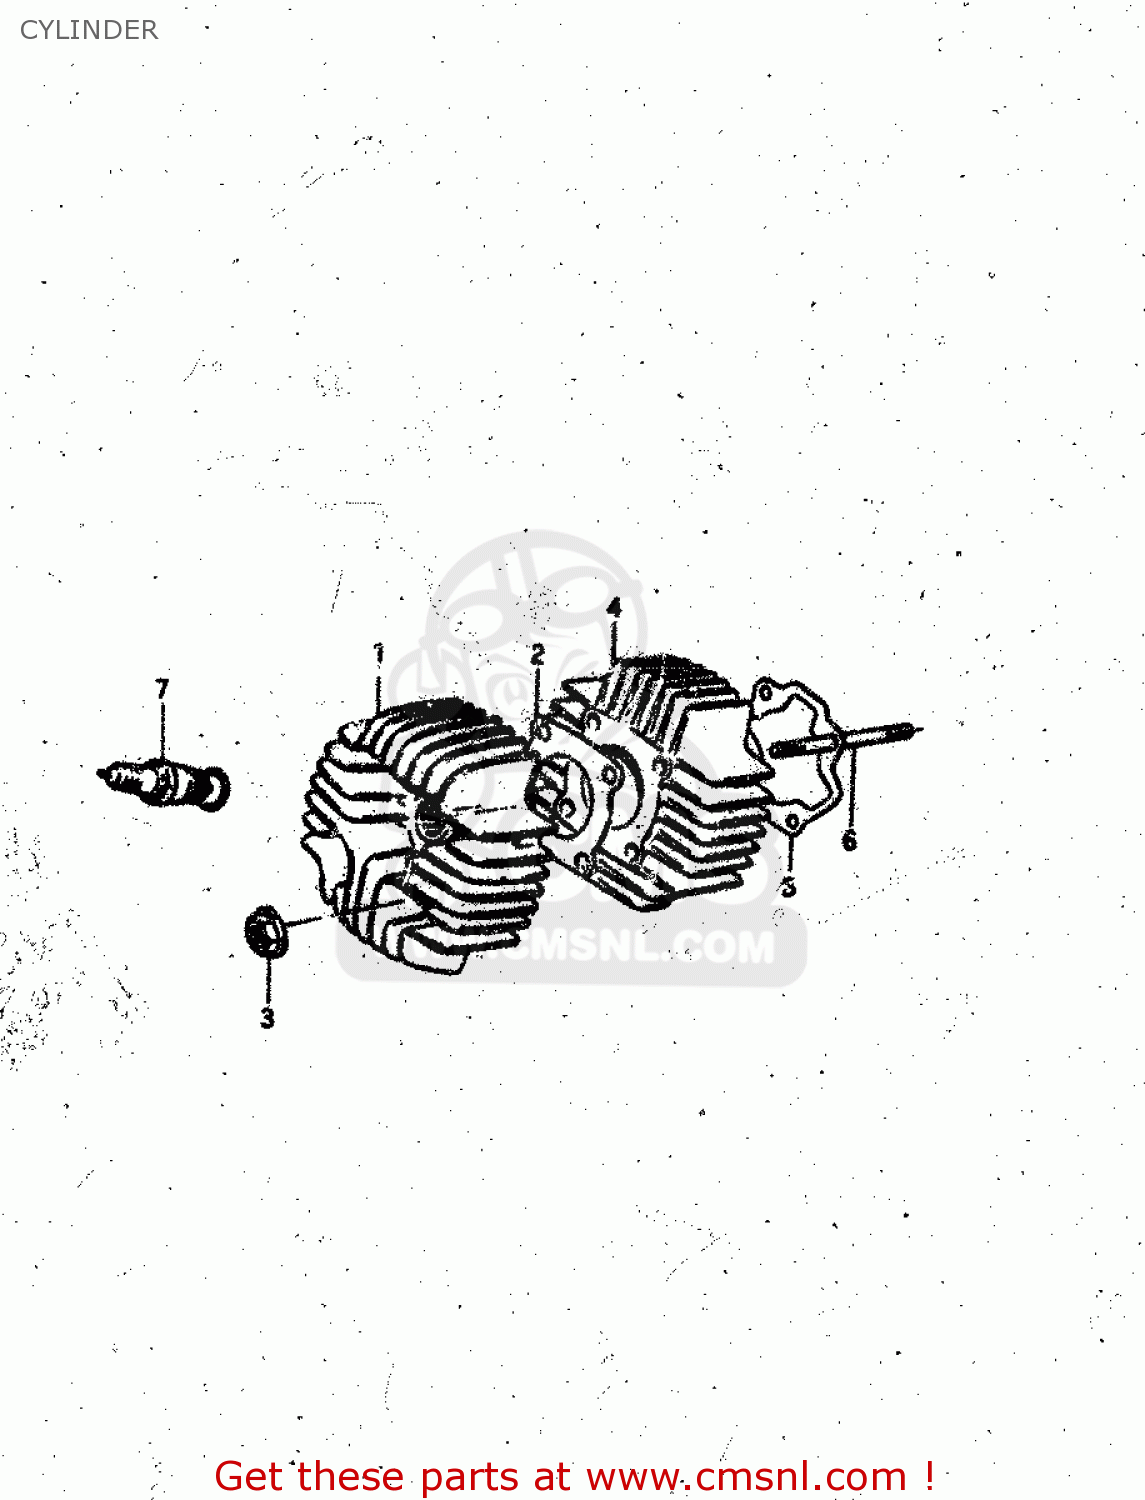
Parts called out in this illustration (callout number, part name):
1	HEAD,CYLINDER
2	GASKET (T:1.5) (NAS)
3	NUT
4	CYLINDER
5	GASKET,CYLINDE (MCA)
6	STUD 6X95
7	SPARK PLUG
